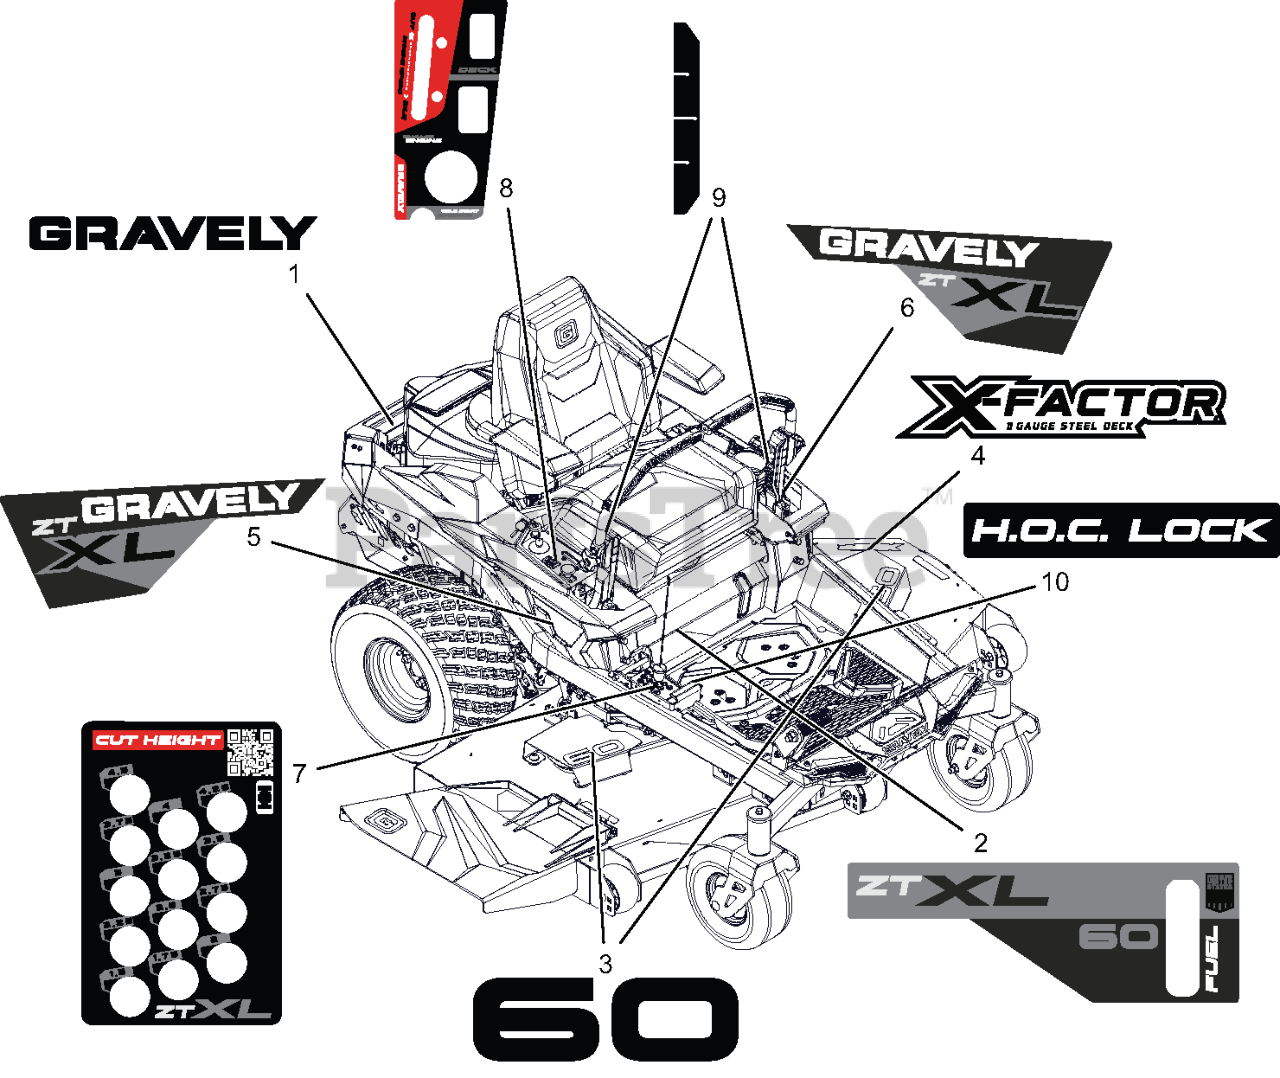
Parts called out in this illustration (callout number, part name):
1	DECAL- GRAVELY
2	DECAL- ZTXL 60-KICK PLATE
3	DECAL- DECK 60"
4	DECAL- DECK X-FACTOR
5	DECAL- ZT XL FENDER RH
6	DECAL- ZT XL FENDER LH
7	DECAL- HEIGHT OF CUT-XL
8	DECAL- CONTROL PANEL-GRAVELY
9	DECAL- HIRTH INDICATOR
10	DECAL- HOC LOCK
